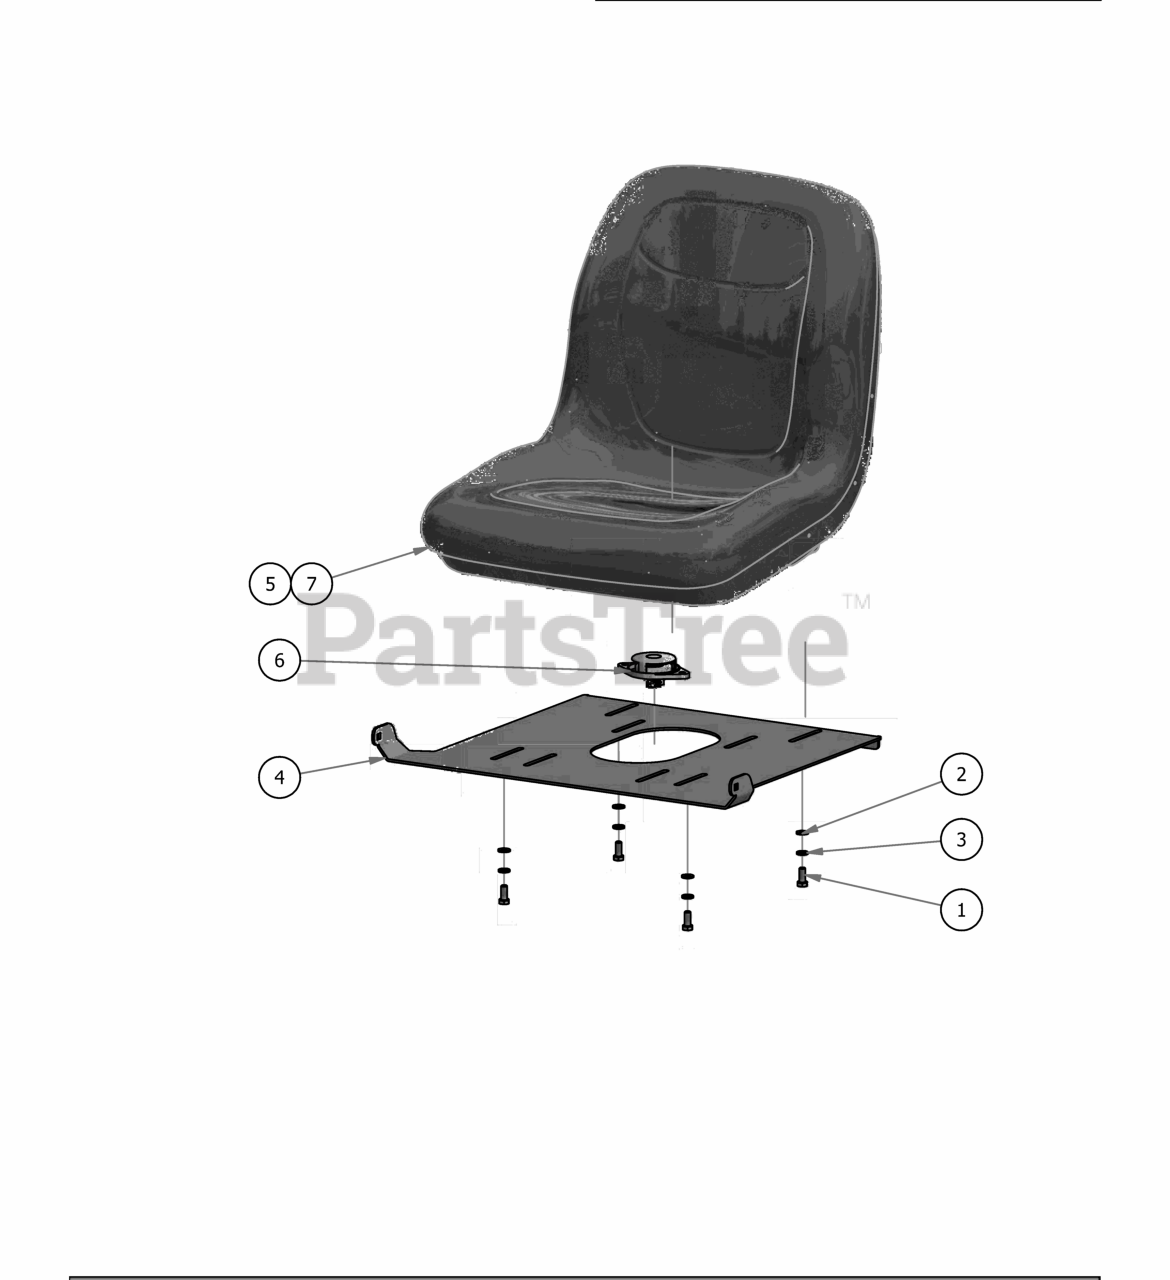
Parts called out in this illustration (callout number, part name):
1	5/16" x 3/4" Hex Bolt
2	1/4" Flat Washer
3	5/16" Lock Washer
4	2017 MZ Seat Plate
5	2019 MZ Magnum Seat
6	SeatSafteySwitch
7	2019 42" MZ Seat
